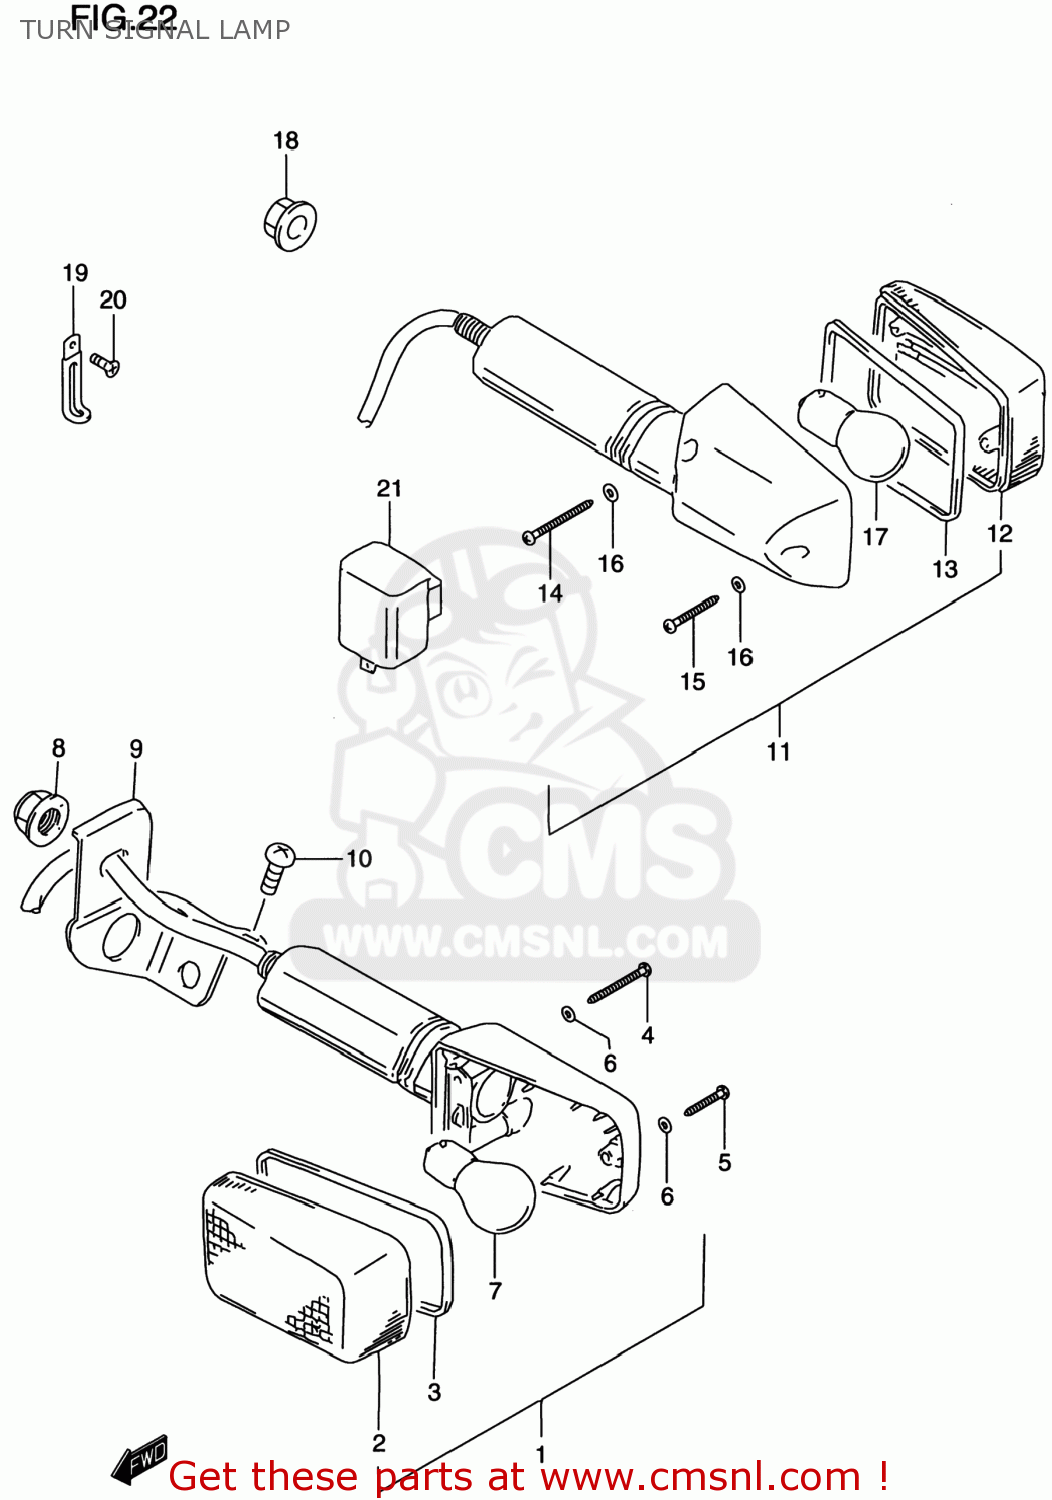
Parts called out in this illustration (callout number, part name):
1	LAMP ASSY,FR TURN SIGNAL
2	LENS
3	GASKET (NAS)
4	SCREW(3X30)
5	SCREW
6	GASKET (NAS)
7	BULB(12V21W)
8	NUT
9	BRACKET,FR TURN,R
10	SCREW
11	LAMP ASSY,RR TURNSIGNAL
12	LENS
13	GASKET (NAS)
14	SCREW(3X30)
15	SCREW
16	GASKET (NAS)
17	BULB(12V21W)
18	NUT
19	CLAMP(L:45)
20	SCREW
21	RELAY ASSY,TURNSIGNAL
